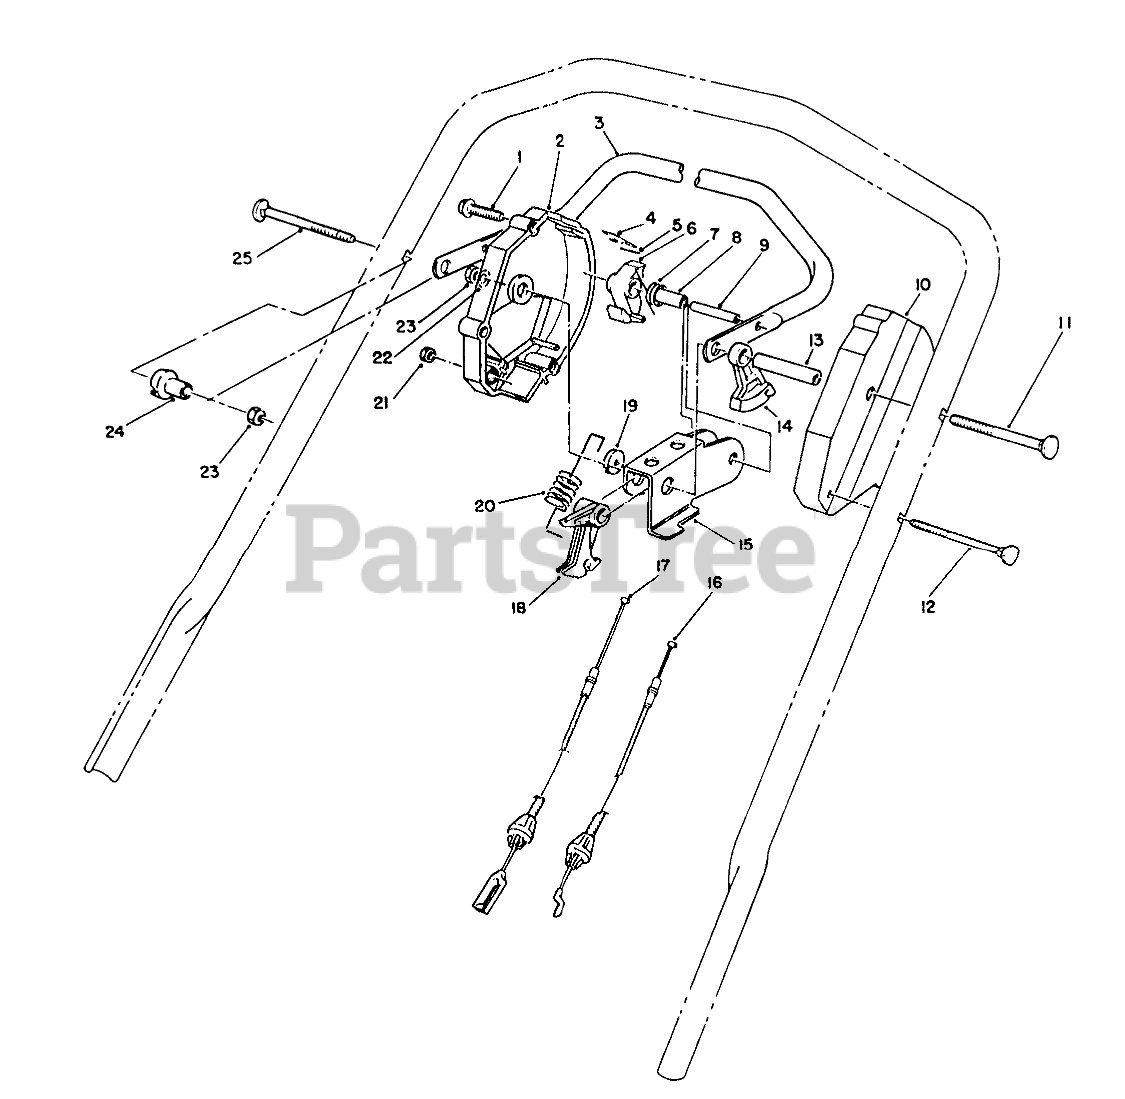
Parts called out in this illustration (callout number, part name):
1	SCREW-HWHTF
2	Housing-Control
3	Bar-Control
4	SPRING-LEAF
5	PIN-INSERT
6	HOOK-CONTROL
7	SPRING-TORSION
8	SPACER
9	PIN-ROLL, SLOTTED
10	HOUSING-CONTROL, LH
11	Screw-Handle
12	HANDLE SCREW
13	TUBING-SPACER
14	LEVER-TRACTION
15	ROCKER
16	TRACTION CABLE
17	BBC CABLE ASSEMBLY
18	LEVER-CABLE
19	WASHER-NYLON
20	SPRING-DETENT
21	NUT-HEX
22	WASHER-PLAIN
23	NUT-LOCK, NI
24	SPACER-SUPPORT
25	SCREW-HANDLE
